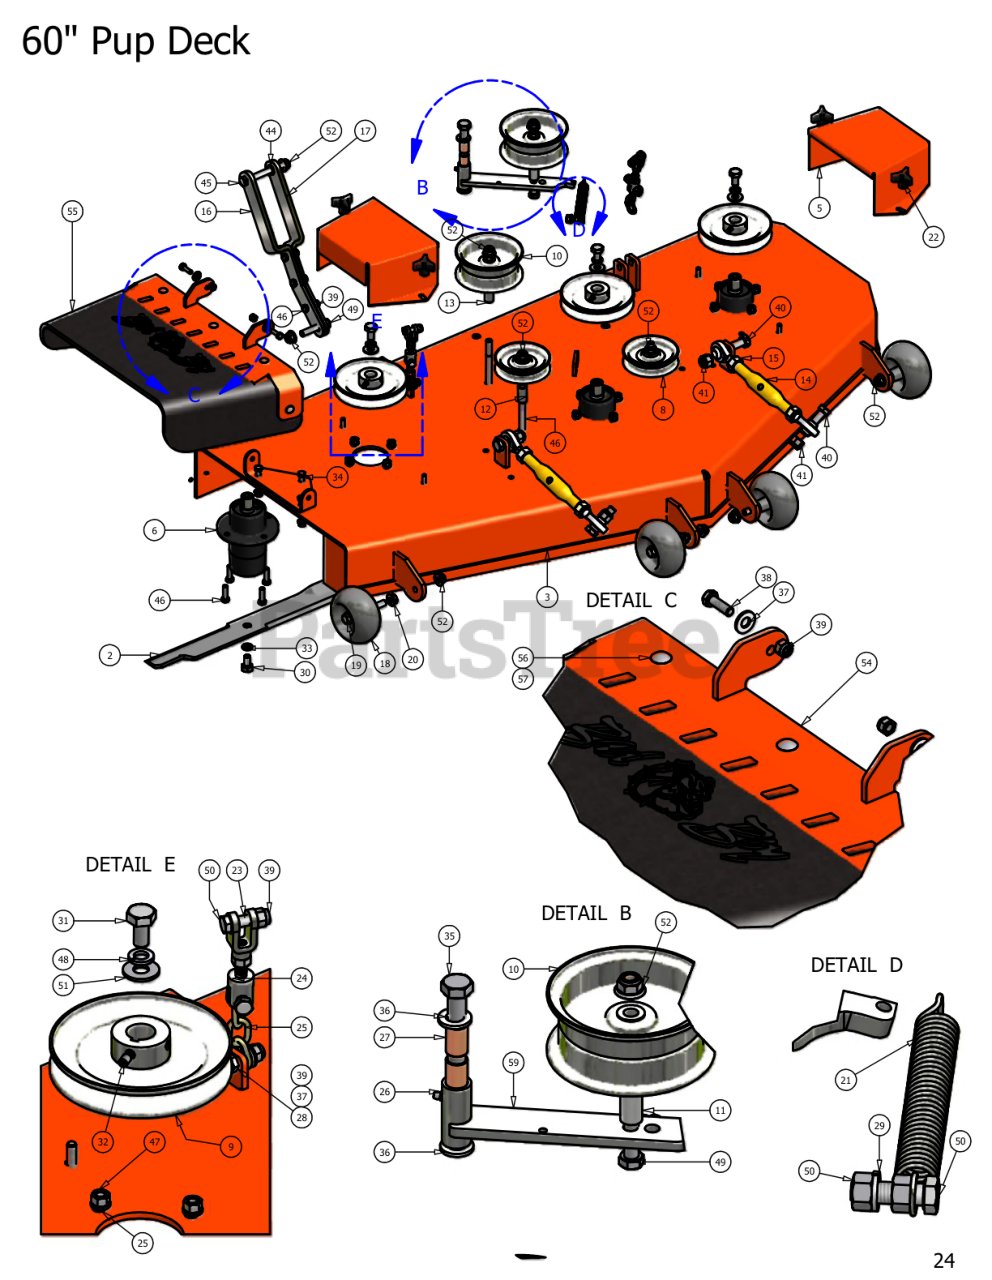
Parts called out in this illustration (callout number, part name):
1	60" Deck Belt
2	60" Fusion Blade
4	Discharge Chute Hanger
5	Pulley Guard
7	Deck Idler Arm
8	4 3/4" Idler Pulley
9	6 1/4" Drive Pulley
10	5 3/4" Flat Idler Pulley
11	1 1/4" Pulley Spacer
12	Pup Pulley Spacer
13	1 3/4" Pulley Spacer
14	Turnbuckle
15	3/4" Left Handed Nut
16	Deck Support Arm(left)
17	Deck Support Arm (Right)
18	Anti-Scalp Rollers
19	1/2" x 4" Bolt (Grade 8)
20	1/2" Flange Nut
21	Deck Idler Spring
22	5/16" Knob
23	Female Yoke
26	Grease Fitting (Drive-In Type)
27	5/8" ID x 1 1/8" Brass Bushing
28	3/8" x 1" Hex Bolt
29	3/8" Lock Washer
30	5/8" x 2" Fine Threaded Bolt
31	1/2" x 1 1/2" Bolt (Fine Threaded)
32	3/8" Set Screw
33	5/8" Lock Washer
34	3/8" x 3/4" Hex Bolt
35	5/8" x 4" Hex Bolt
36	.635 ID Plastic Washer
37	.360 ID Plastic Washer
38	5/16" x 1" Hex Bolt
39	5/16" Nylock Nut
40	5/8" x 2 1/2" Hex Bolt
41	5/8 Std NC Nylock Nut
42	1/2" x 3 1/2" Bolt
44	1/2" Brass Washer
45	1/2" x 4 1/2" Bolt
46	3/8" x 1 1/4" Hex Bolt
47	3/8" Hex Nut
48	1/2" Lock Washer
49	1/2" x 2 1/2" Hex Bolt
50	3/8" x 1 1/2" Hex Bolt
51	1/2" Cupped Washer
52	1/2" Flange Lock Nut
53	2007 Lower Hanger Plate
54	2007 Hanger Plate
55	Rubber Side Discharge
56	5/16" x 1 1/2" Carriage Bolt
57	5/16" Nylock Flange Nut
